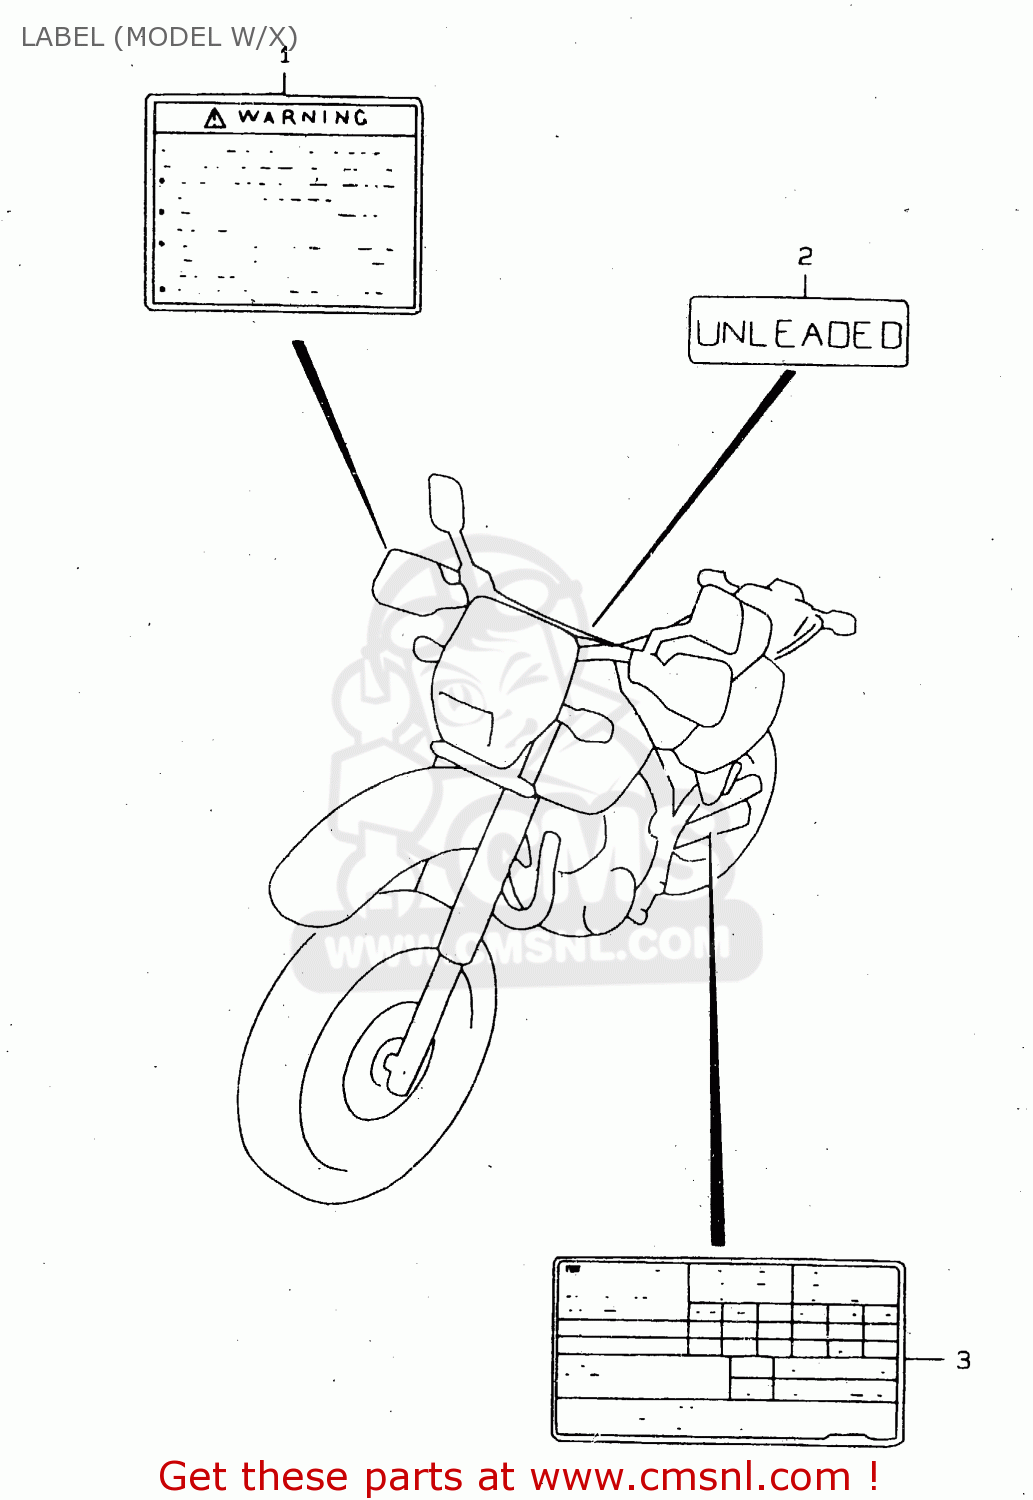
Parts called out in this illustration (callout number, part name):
1	LABEL,WARNING
2	LABEL,CAUTION
3	LABEL, TIRE AIR PRESSURE
4	MANUAL, OWNER'S
